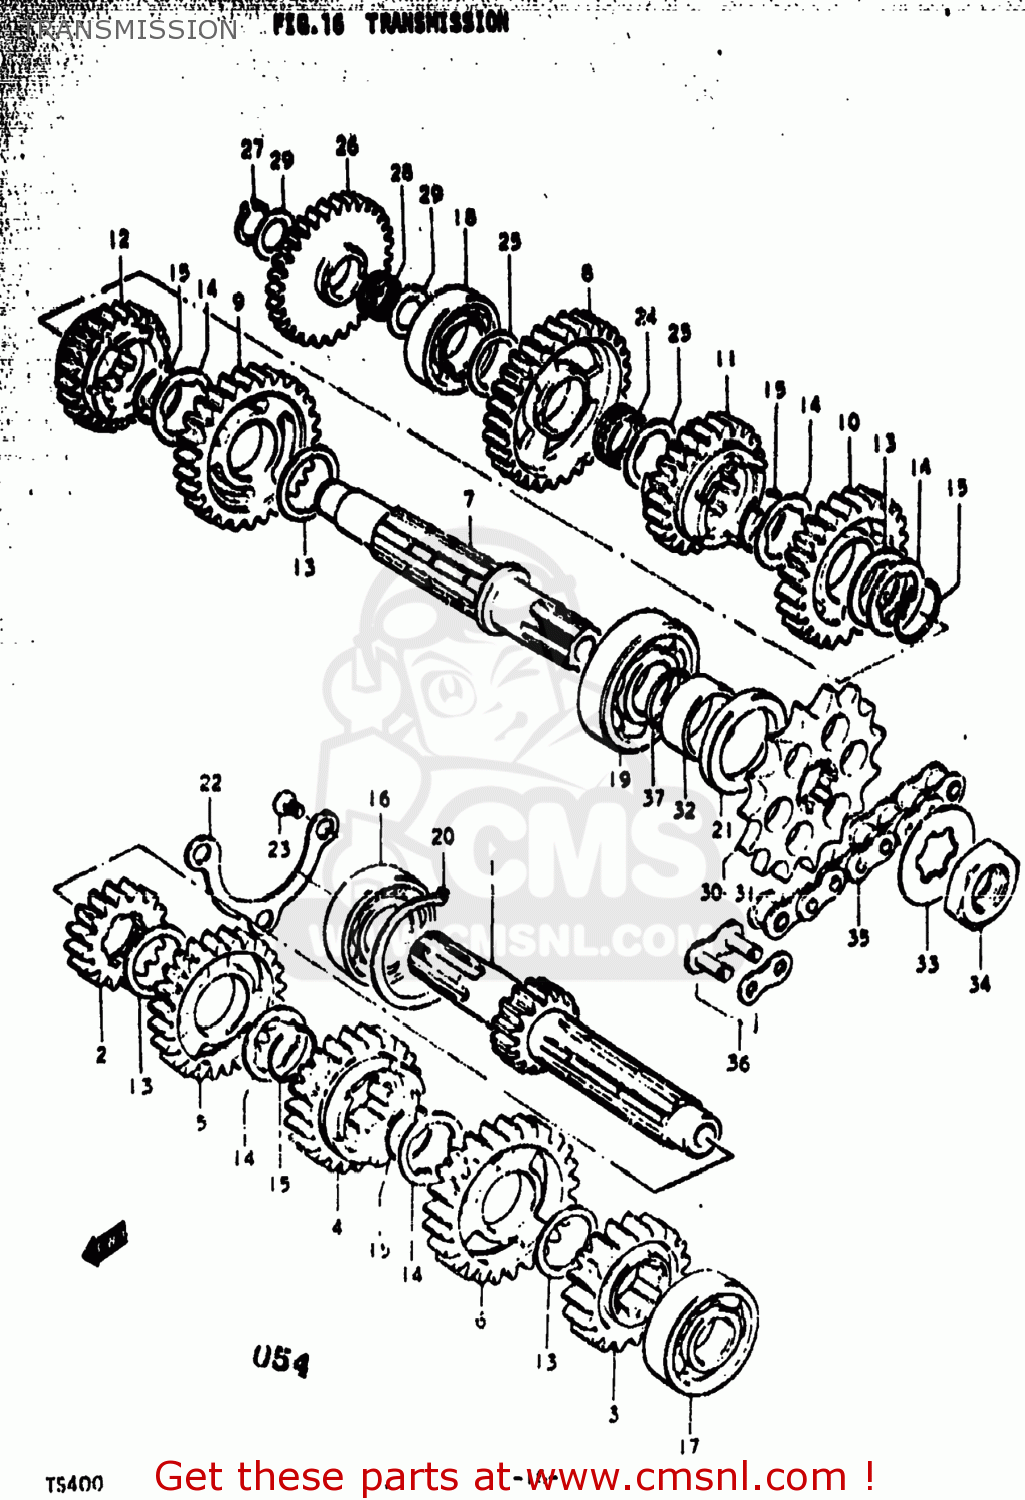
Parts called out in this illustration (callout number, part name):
1	SHAFT,COUNTER
3	GEAR,SECOND DRIVE
4	GEAR,THIRD DRIVE
5	GEAR,FOURTH DRIVE
6	GEAR,FIFTH DRIVE
7	SHAFT,DRIVE
8	GEAR,FIRST DRIVEN
9	GEAR,SECOND DRIVEN
10	GEAR,THIRD DRIVEN
11	GEAR,FOURTH DRIVEN
12	GEAR,FIFTH DRIVEN
13	WASHER
14	WASHER
15	RING,SNAP
16	BEARING
17	Bearing
18	Bearing
19	BEARING
20	CIRCLIP
21	SEAL,OIL(32X42X6)
22	RETAINER,BEARING
23	SCREW
24	BEARING
25	WASHER (20X30X1)
26	GEAR,KICK STARTER IDLE
27	CIRCLIP
28	BEARING(17X21X9.8)
29	WASHER
30	SPROCKET,ENGINE
31	SPROCKET,ENGINE
32	SPACER (22X32X13.4)
33	WASHER,LOCK
34	NUT
35	CHAIN ASSEMBLY,DRIVE
36	JOINT ASSEMBLY,CHAIN
37	O RING(D:1.7,ID:22)
